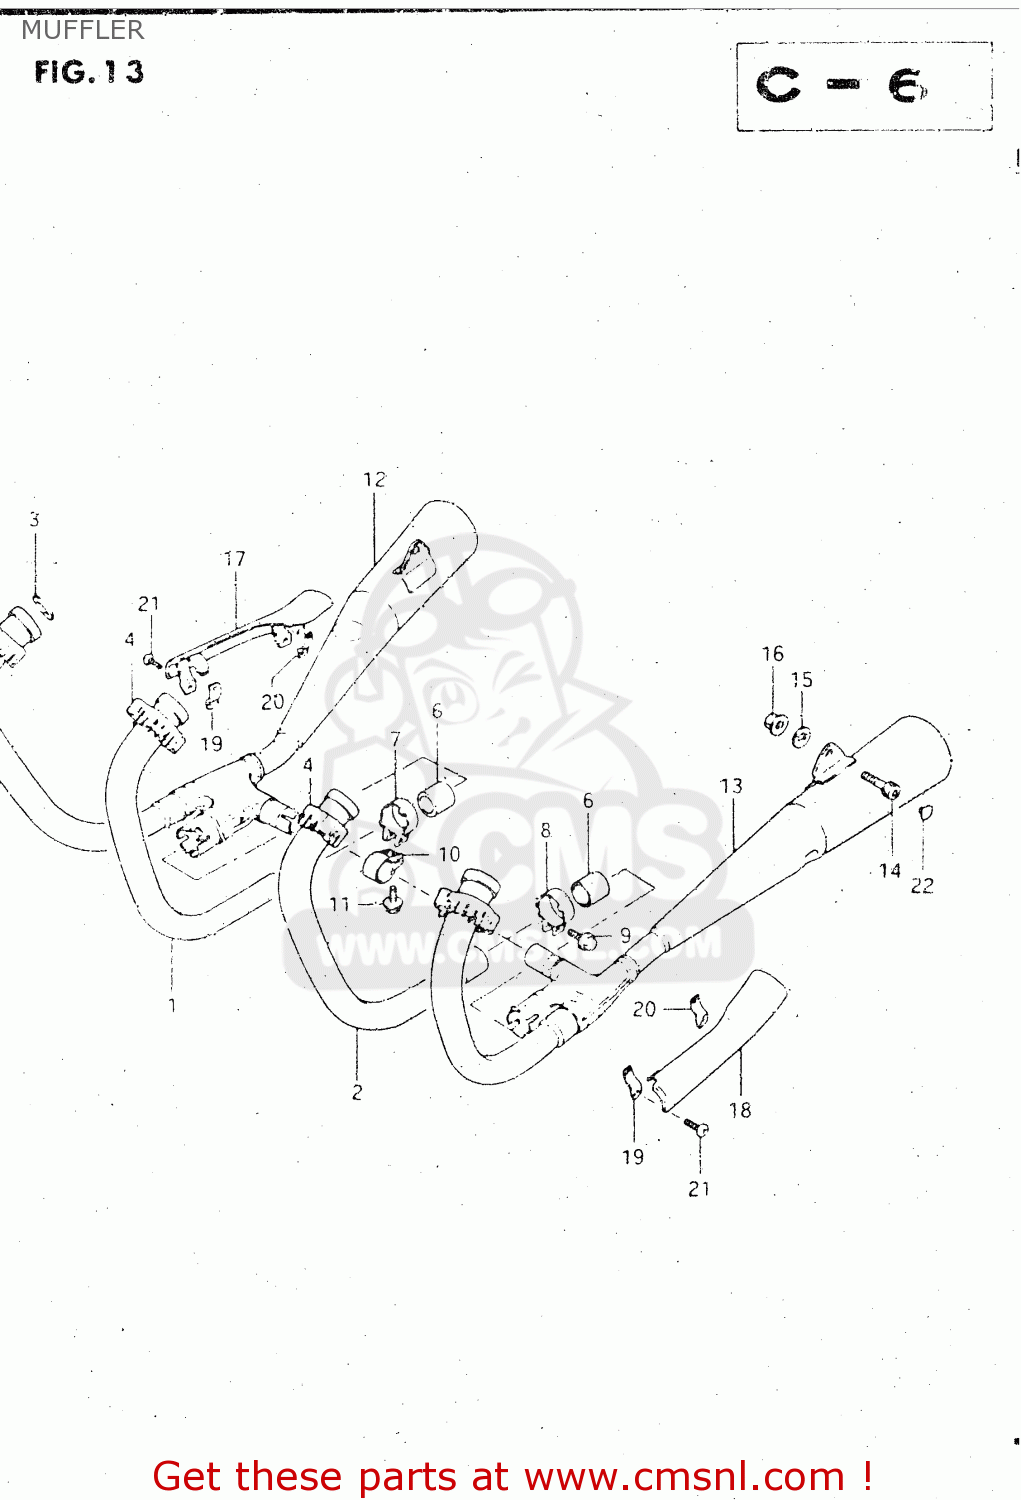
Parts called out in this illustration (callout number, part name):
1	PIPE,EXHAUST,CENTER,RIGHT
2	PIPE,EXHAUST,CENTER,LEFT
3	GASKET,EXHAUST PIPE (NAS)
4	CLAMP,EXHAUST PIPE
5	BOLT
6	CONNECTOR,MUFFLER
7	CLAMP,MUFFLER CONNECTOR
8	CLAMP,MUFFLER CONNECTOR
9	BOLT
10	CLAMP,EXHAUST
11	BOLT
12	MUFFLER, RH
13	MUFFLER, LH
14	BOLT
15	WASHER(10.5X20X3.2)
16	NUT
17	COVER,MUFFLER,RIGHT
18	COVER,MUFFLER,LEFT
19	CLAMP,MUFFLER COVER
20	CLAMP,MUFFLER COVER
21	SCREW
22	CAP
